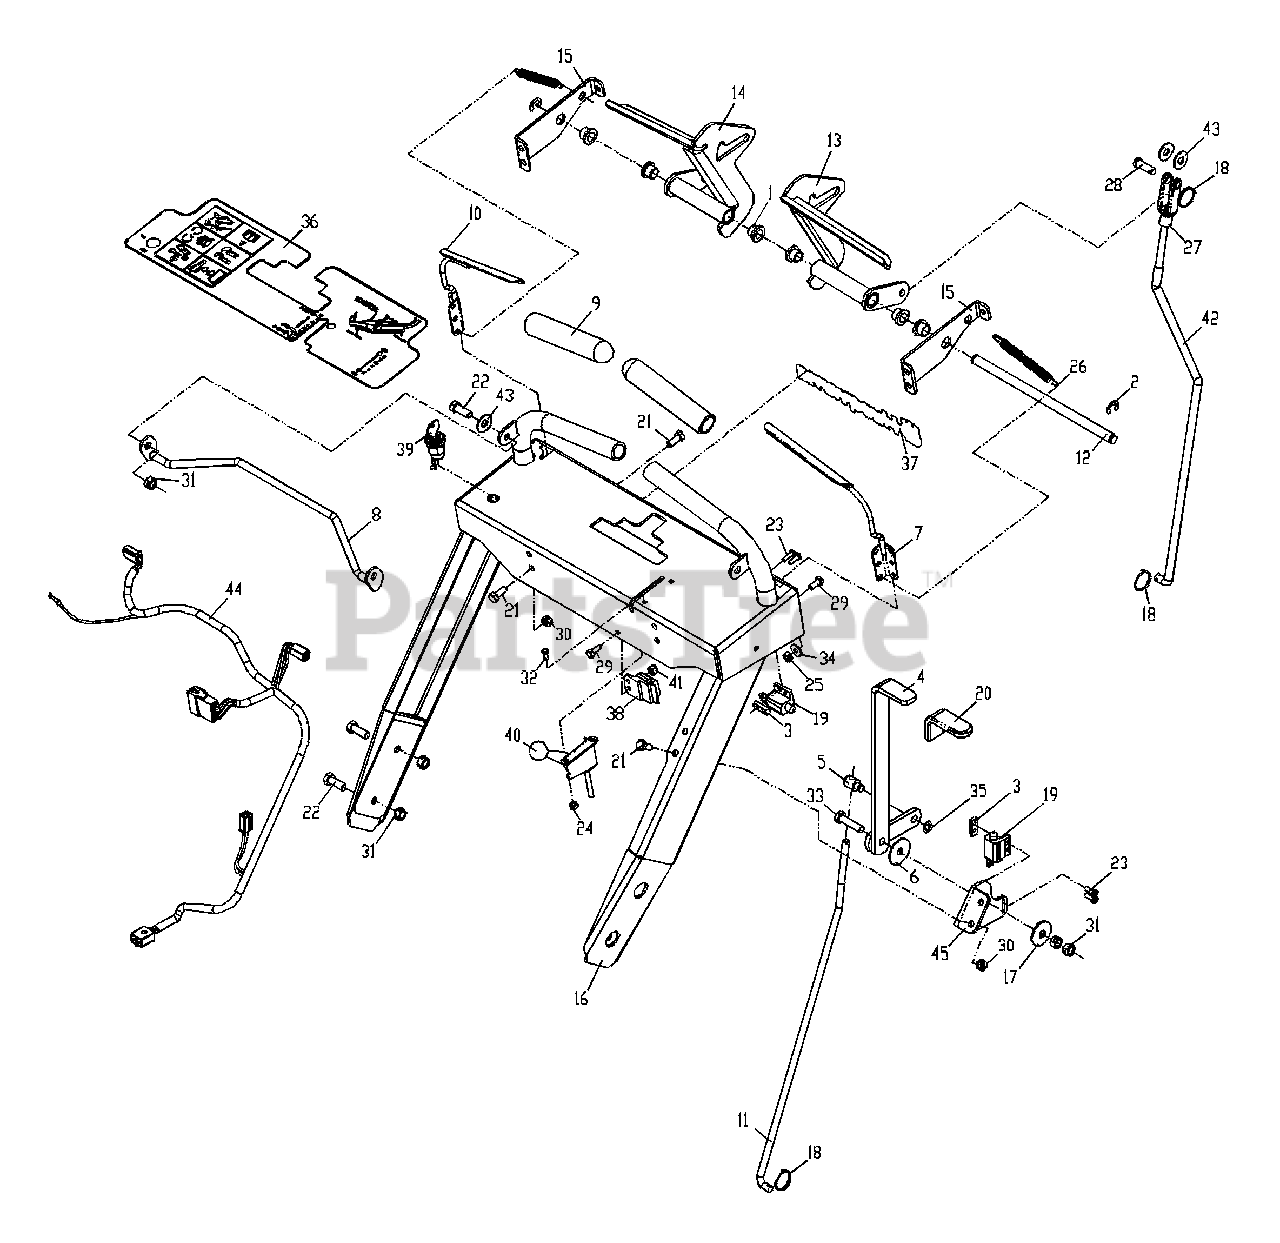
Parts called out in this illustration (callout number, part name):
1	BUSHING, FLANGED NYLON
2	E-RING 1/2"
3	TAPPED PLATE
4	ENGAGEMENT LEVER
6	WASHER, FRICTION
7	OP LEVER, LT.
8	NEUTRAL BAIL
10	OP LEVER, RT.
11	BLADE ENGAGE. LINKAGE
12	CENTER PIVOT SHAFT
13	DRIVE LVR. WLDMT. LT.
14	DRIVE LVR. WLDMT RT.
15	SUPPORT BRACKET
16	HANDLE WLDMT.
17	WASHER, CONE
18	RETAINER RING
21	HCS 5/16 X .750
22	HCS 3/8 X 1.0
23	SCREW #10 X .625
24	NUT #10 NYLOC
25	NUT 1/4 LOCK
28	CLEVIS PIN
29	HCS 1/4 X .625
30	NUT 5/16 LOCK
31	NUT 3/8 LOCK
32	# 10 X .500
33	HCS 3/8 X 1.5
34	WASHER 1/4 FLAT
36	DECAL, CONSOLE
37	DECAL, HUSQVARNA
39	KEY SWITCH
40	THROTTLE CABLE
41	NUT 1/4 NYLOC
42	DRIVE LINKAGE
43	WASHER 3/8 FLAT
44	UPPER HARNESS
45	BLADE ENGAGE. BRACKET
